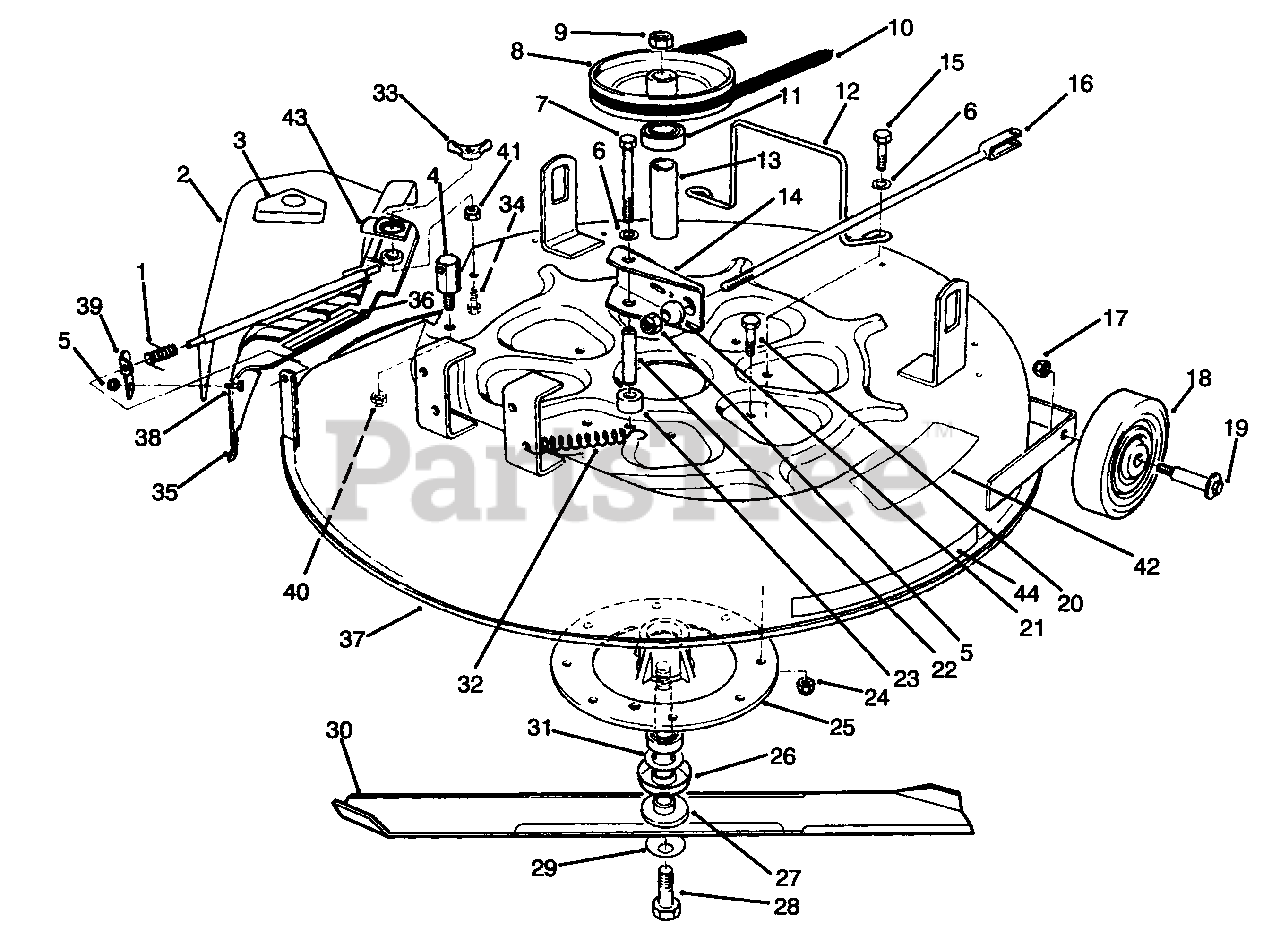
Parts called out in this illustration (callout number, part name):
2	Deflector (Incl. Ref. #3)
3	Decal-Danger
4	Post-Pivot
5	Nut-Lock
6	Washer-Lock
7	Screw-Cap Hex. Hd.
8	Pulley-Deck
9	Nut-Hex.
10	V-Belt
11	Bearing-Ball
12	Guide- Belt
13	Spacer-Bearing
14	Assy.-Brake, Deck
15	Screw-Cap Hex. Hd.
16	Rod W.A.-Brake, Deck
17	Nut-Lock
18	Wheel-Deck
19	Bolt-Wheel
20	Screw-Cap Hex. Hd.
21	Ball-Swivel
22	Post-Mount, Brake
23	Spacer-Brake, Deck
24	Nut-Lock
25	Hub-Spindle
26	Shield-Bearing
27	Shaft-Spindle
28	Bolt-Blade
29	Washer-Belleville
30	Blade-Power Mulch
31	Spacer-Spindle
32	Spring-Brake
33	Nut-Wing
34	Screw-Cap Hex. Hd.
35	Cover-Easy Mulch
36	Decal-Warning
38	Screw-Cap Hex. Hd.
39	Bracket-Deflector
40	Nut-Lock
41	Nut-Lock
42	Decal-Danger
43	Tab-Hold Down
44	Decal-Easy Mulch
